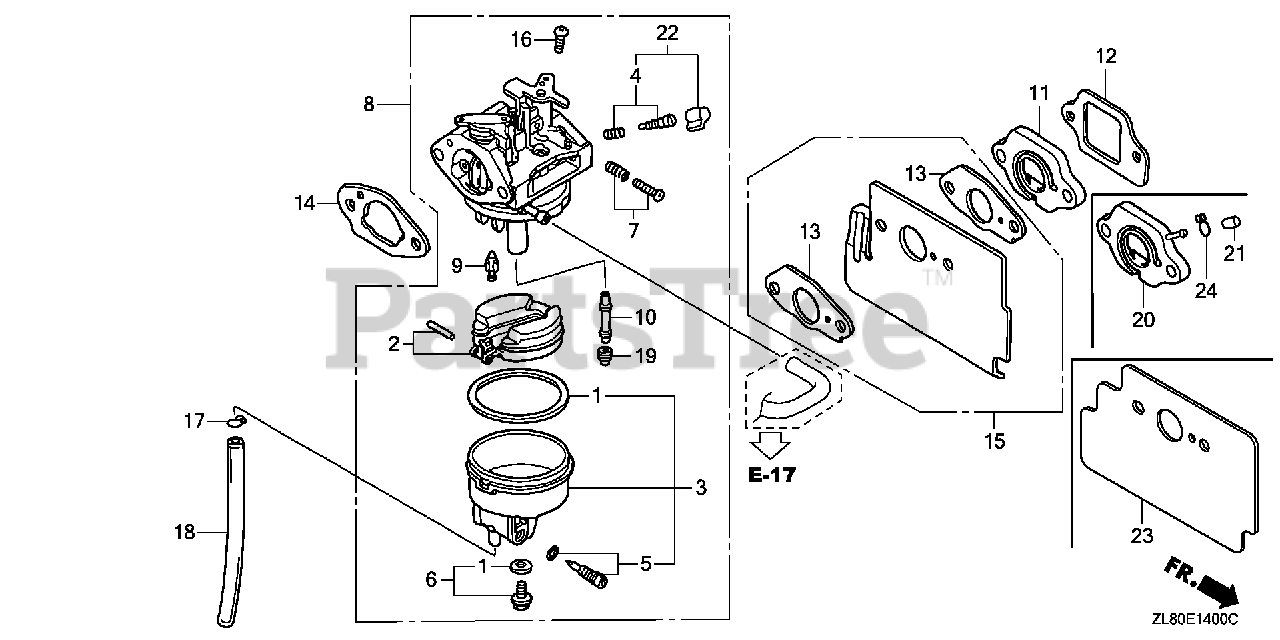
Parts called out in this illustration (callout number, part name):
1	GASKET SET
3	CHAMBER SET, FLOAT
5	SCREW SET, DRAIN
6	SCREW SET
7	SCREW SET (THROTTLE STOP) (CARBURETOR NO.)
8	CARBURETOR ASSY. (BB61B C)
8	CARBURETOR ASSY. (BB61B D)
9	VALVE, FLOAT (CARBURETOR NO.)
10	NOZZLE, MAIN (CARBURETOR NO.)
11	INSULATOR, CARBURETOR
12	GASKET, INSULATOR
13	GASKET, CARBURETOR
14	GASKET, CARBURETOR
15	GUIDE, AIR
16	SCREW, PAN (5X6)
17	CLIP, TUBE (B6.5)
18	BULK HOSE, VINYL (4X7X8000) (4X7X150)
19	JET, MAIN (#60)
19	JET, MAIN (#62)
19	JET, MAIN (#65)
22	SCREW SET (CARBURETOR NO.)
